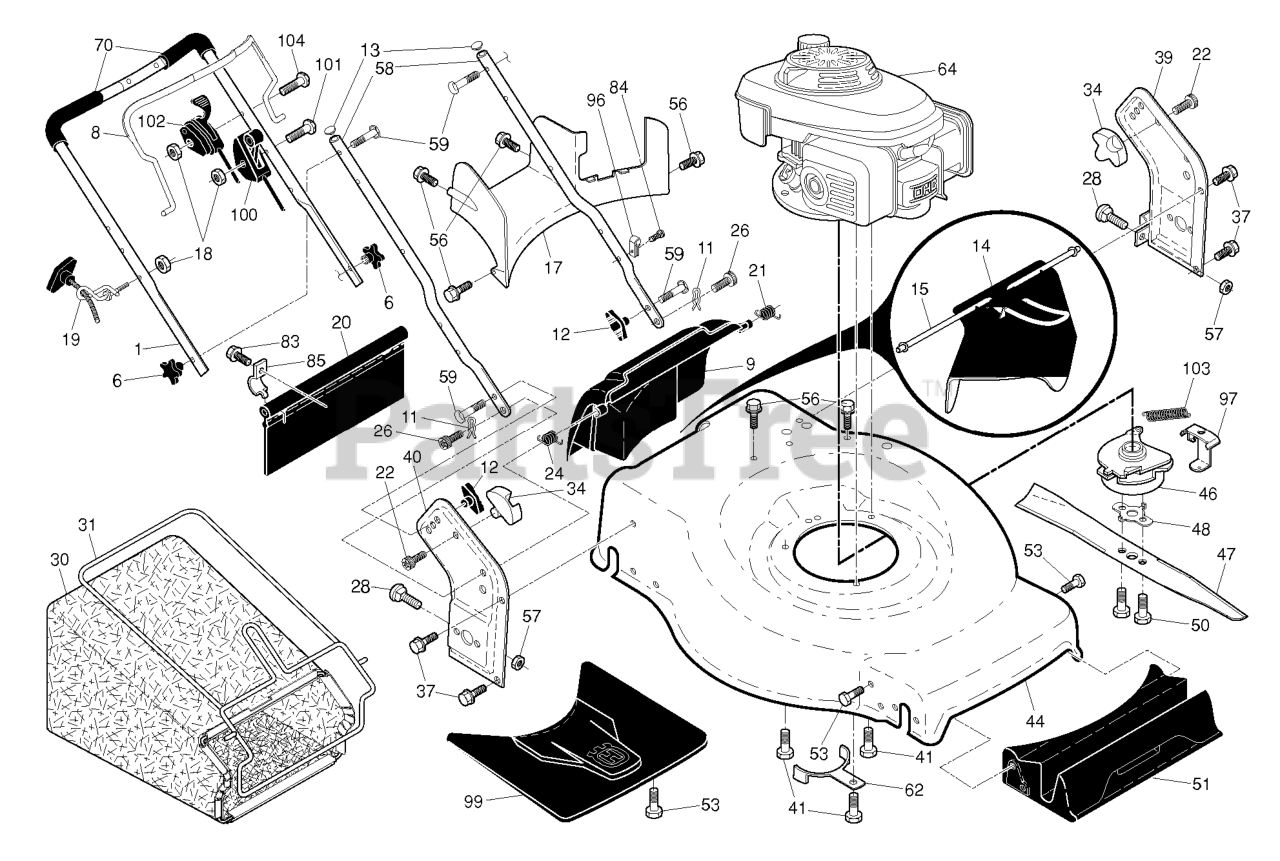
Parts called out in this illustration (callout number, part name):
1	HANDLE.ASM.UPPER.W/GRIP
6	KNOB.HANDLE.PLASTIC.STAR.BLACK
8	BAIL.CONTROL.HV.BBC.ORANGE
9	DOOR.REAR.ASM.22+.HUSQ.FG/RGD
11	COTTER.HAIRPIN.DOOR/HANDLE.PIV
12	KNOB, DEFLECTOR
13	PLUG.PLASTIC.7/8".14-20.GAUGE
14	DEFLECTOR.CHUTE.22+REAR
15	HANDLE DEFLECTOR.22+REAR
17	RP.BAFFLE.REAR.22+.RGD.PL
18	NUT
19	RB GUIDE.ROPE.STD.BLK.ZIN WSL
20	SKIRT.REAR.22PLUS.RGD.LW(2 2MC
21	SPRING.LH.BLACK
22	SCREW.PAN.HEAD.#10
24	SPRING.RH.GRAY
26	SCREW,DOOR/HANDLE.PIVOT
28	BOLT
30	GBAG.A3610247T.SILV.HUSWT.BLUE
31	RB FRAME.GBAG.22PLUS
34	BRACKET.GRASSBAG.ATTACHING.BLK
37	BOLT.5/16HEX.WHS.HD
39	BRACKET.HANDLE.LT.22+.W/DP.GRE
40	RP.BRACKET.ASM.HANDLE.RT.22+.
41	BOLT 3/8-16X1-1/8
44	HOUSING.22+.RWD.HD.WO/PORT.ORA
47	BLADE.FUSION.HONDA.BBC.HUSQ.
48	SPACER.BLADE.HONDA.BBC
50	BOLT.BLADE
51	BAFFLE.FRONT.22PLUS.PLASTIC RP
53	SCREW.HI-LO.5/16 X.75
56	SCREW.HX.13X.750
57	NUT.FLANGE.5/16
58	HANDLE.LOWER.22+BT.2PC.GRY
59	BOLT, HANDLE 5/16-18X1.75
62	BRACKET.KEEPER.BELT
70	GRIP.HANDLE.FOAM.WIDE.(1 SIDE)
83	TAPPING SCREW
84	FASTENER.PUSH.O.250X0.783
85	BRACKET.SKIRT.22+.BZP
96	CLIP.CABLE.BLK
97	BRACKET.BBC.MOUNTING
99	COVER.ASM.FRONT.SHROUD.HUSQ.
100	CONTROL.THROTTLE.HOND.BBC.58.5
102	CONTROL.HONDA.GREY/BLACK
103	SPRING.BBC
